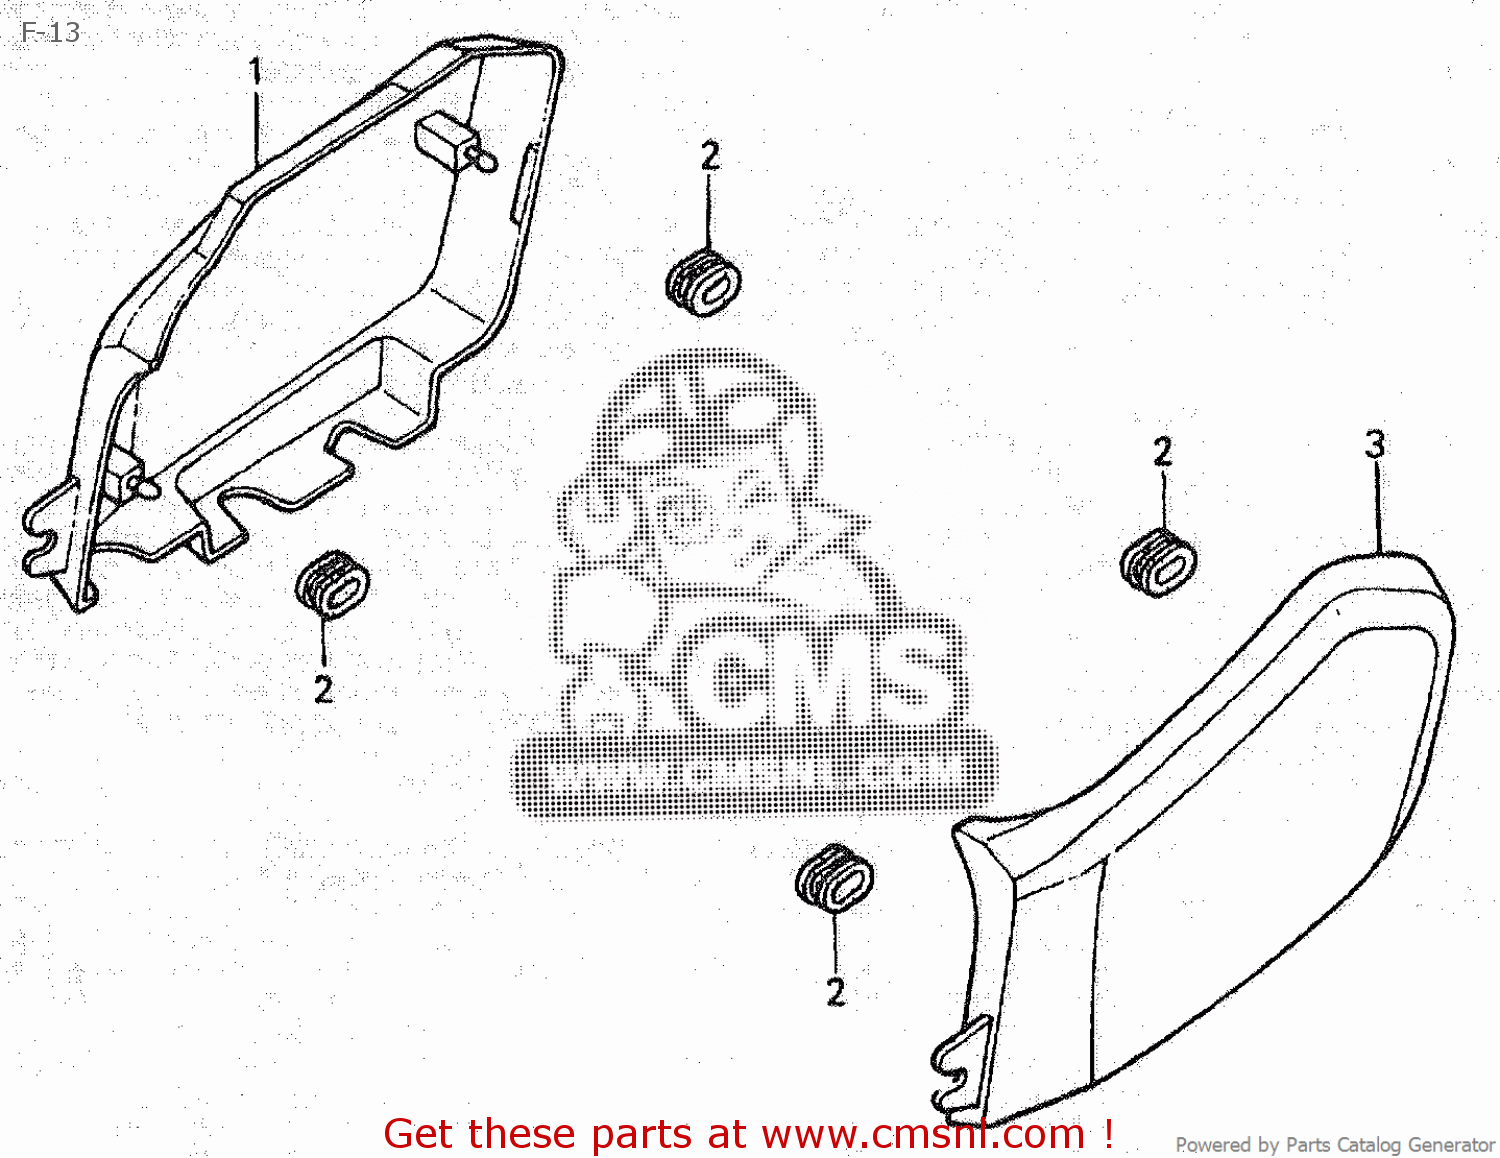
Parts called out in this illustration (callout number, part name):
1	COVER,*PB-127C-U* (JDM)
2	CASE,GROMET
3	COVER,*PB-127C-U* (JDM)
